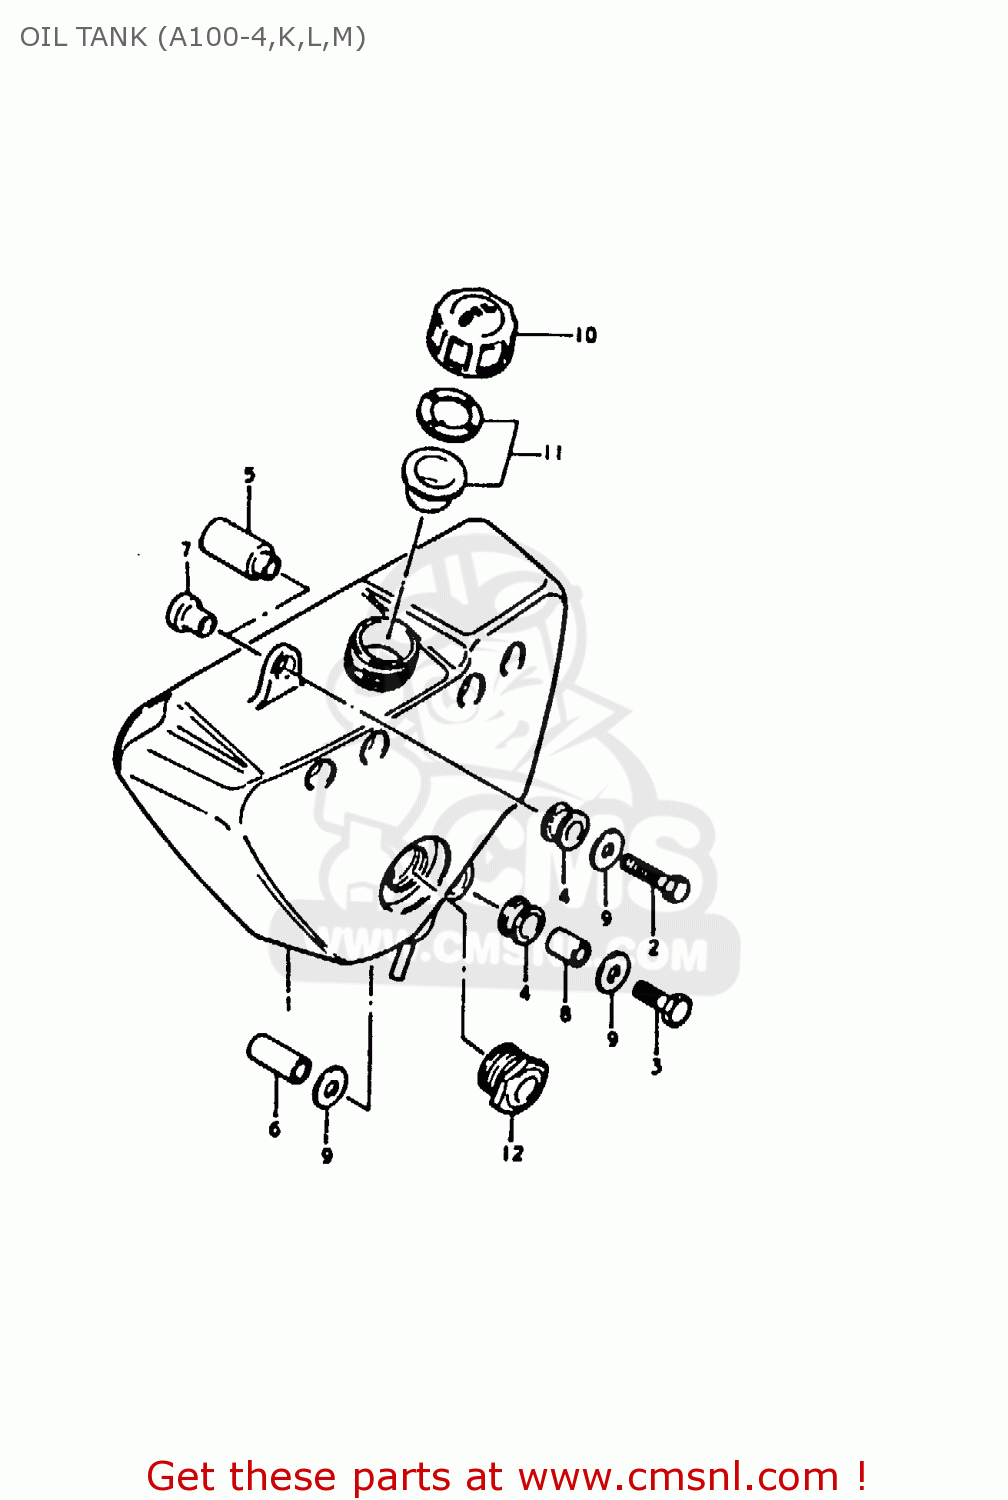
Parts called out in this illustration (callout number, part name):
1	TANK, OIL
2	BOLT
3	BOLT
4	CUSHION
5	SPACER, UPPER
6	SPACER (6.5X10.5X13.5)
8	SPACER (6.8X10X10)
9	WASHER
10	CAP,OIL TANK
11	LENS,OIL LEVEL INSPECTION
12	LENS,OIL LEVEL INSPECTION
